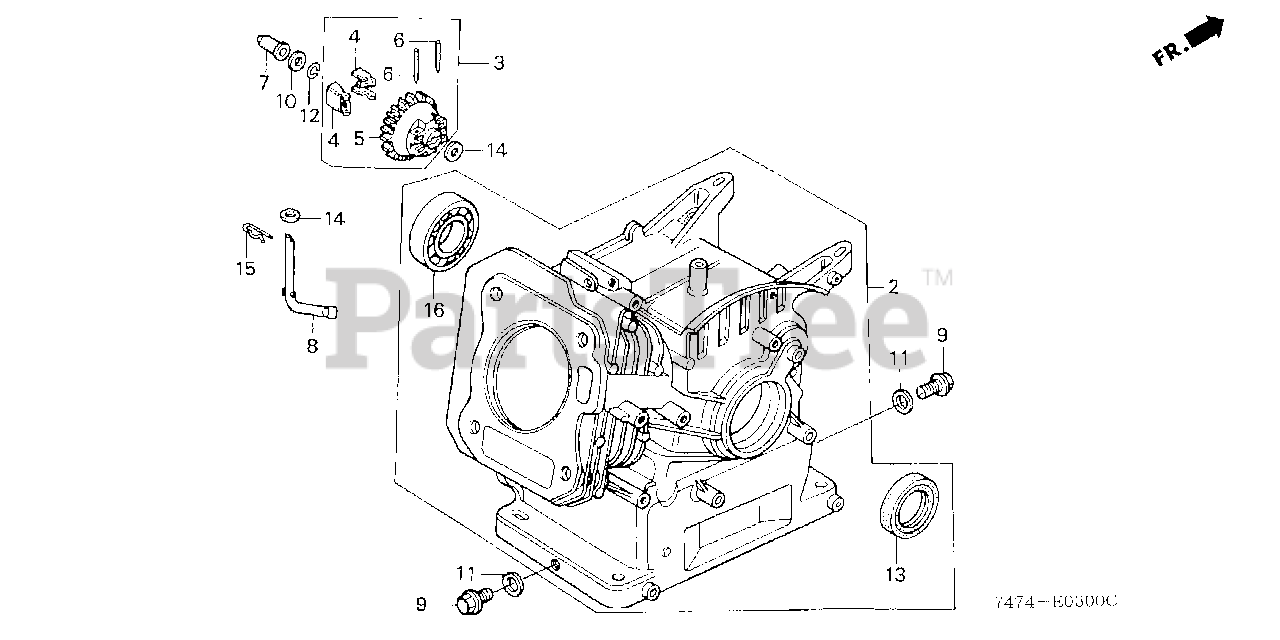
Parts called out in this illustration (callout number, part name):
2	CYLINDER ASSY.
3	GOVERNOR ASSY.
4	WEIGHT, GOVERNOR
5	HOLDER, GOVERNOR WEIGHT
6	PIN, GOVERNOR WEIGHT
7	SLIDER, GOVERNOR
8	SHAFT, GOVERNOR ARM
9	BOLT, DRAIN PLUG
10	WASHER, THRUST (6MM)
11	WASHER, DRAIN PLUG (10.2MM)
12	CLIP, GOVERNOR HOLDER
13	OIL SEAL (25X41X6)
14	WASHER, PLAIN (6MM)
15	PIN, LOCK (8MM)
16	BEARING, RADIAL BALL (6205)
